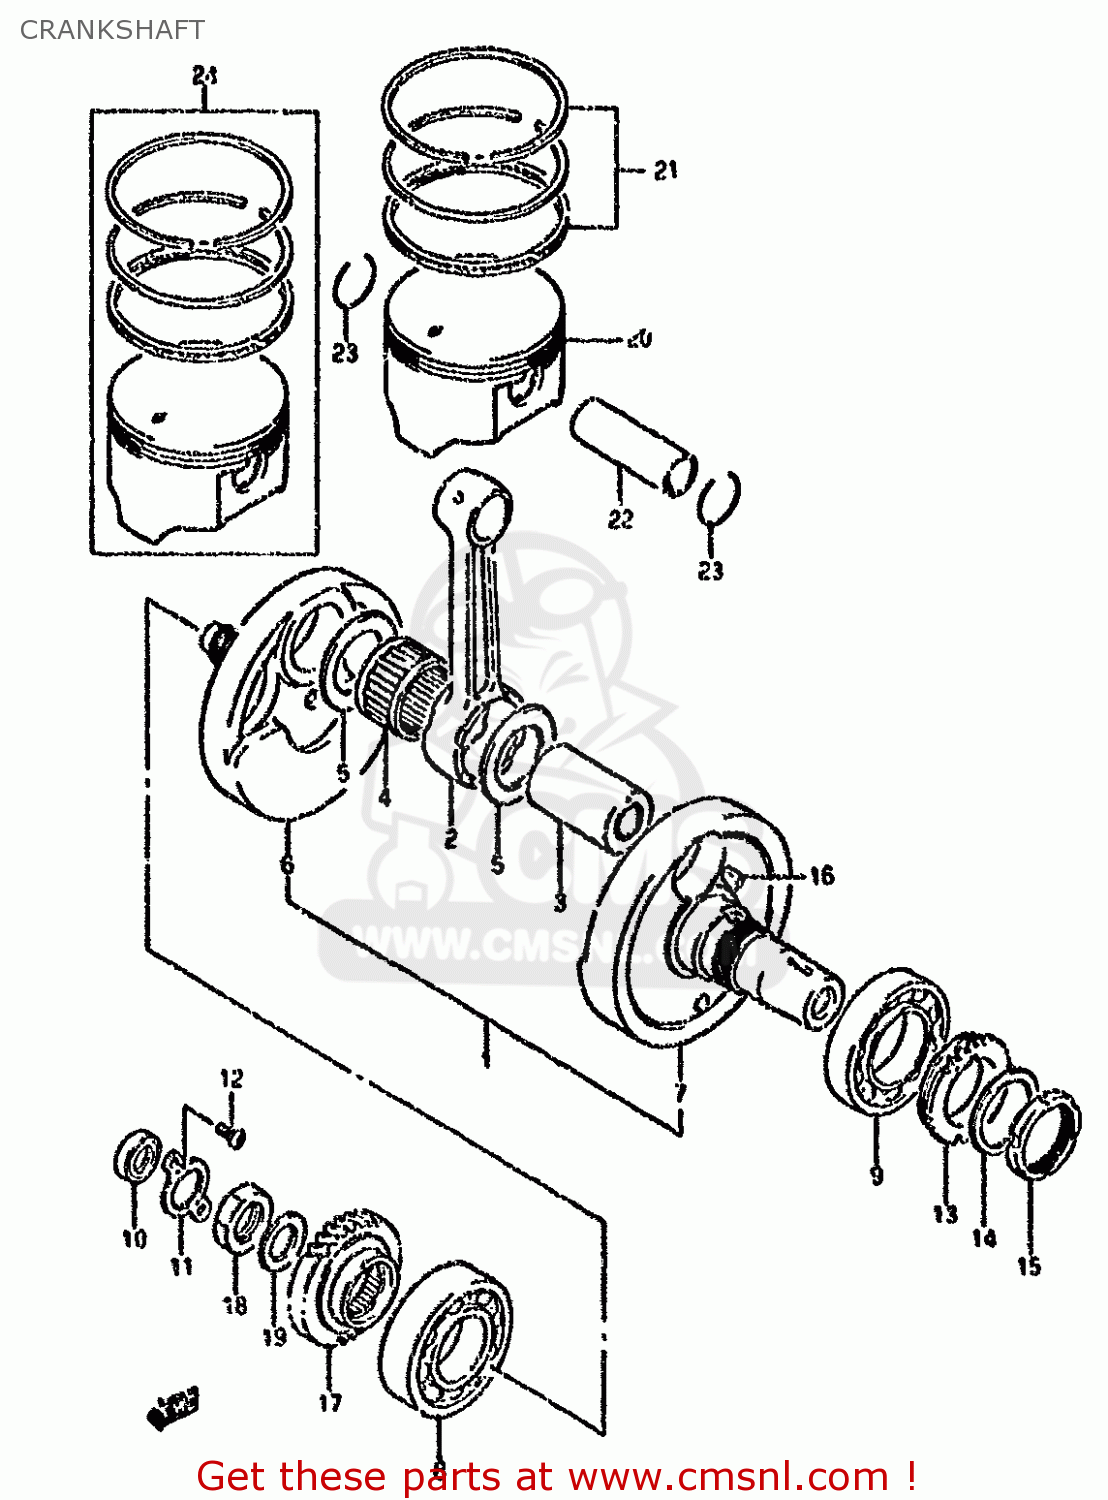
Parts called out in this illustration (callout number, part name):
1	CRANKSHAFT ASSY
2	ROD,CONNECTING
3	PIN,CRANK
4	BEARING(41X51X24.8)
5	WASHER(41X61X1)
6	CRANKSHAFT, RH
7	CRANKSHAFT, LH
8	BEARING(40X90X23)
9	BEARING(45X85X19)
10	SEAL,OIL(16X30X6)
11	RETAINER,CRANKSHAFT BEARING,R
12	SCREW
13	SPROCKET,BAL.D
14	WASHER
15	NUT,BAL DRIVE SPRKT
16	KEY
17	GEAR, PRIMARY DRIVE (NT:33)
18	NUT
19	WASHER
20	PISTON (105.00MM)
21	RING SET,PISTON
22	PIN,PISTON
23	CIRCLIP
24	PISTON SET(OS:0.5)
